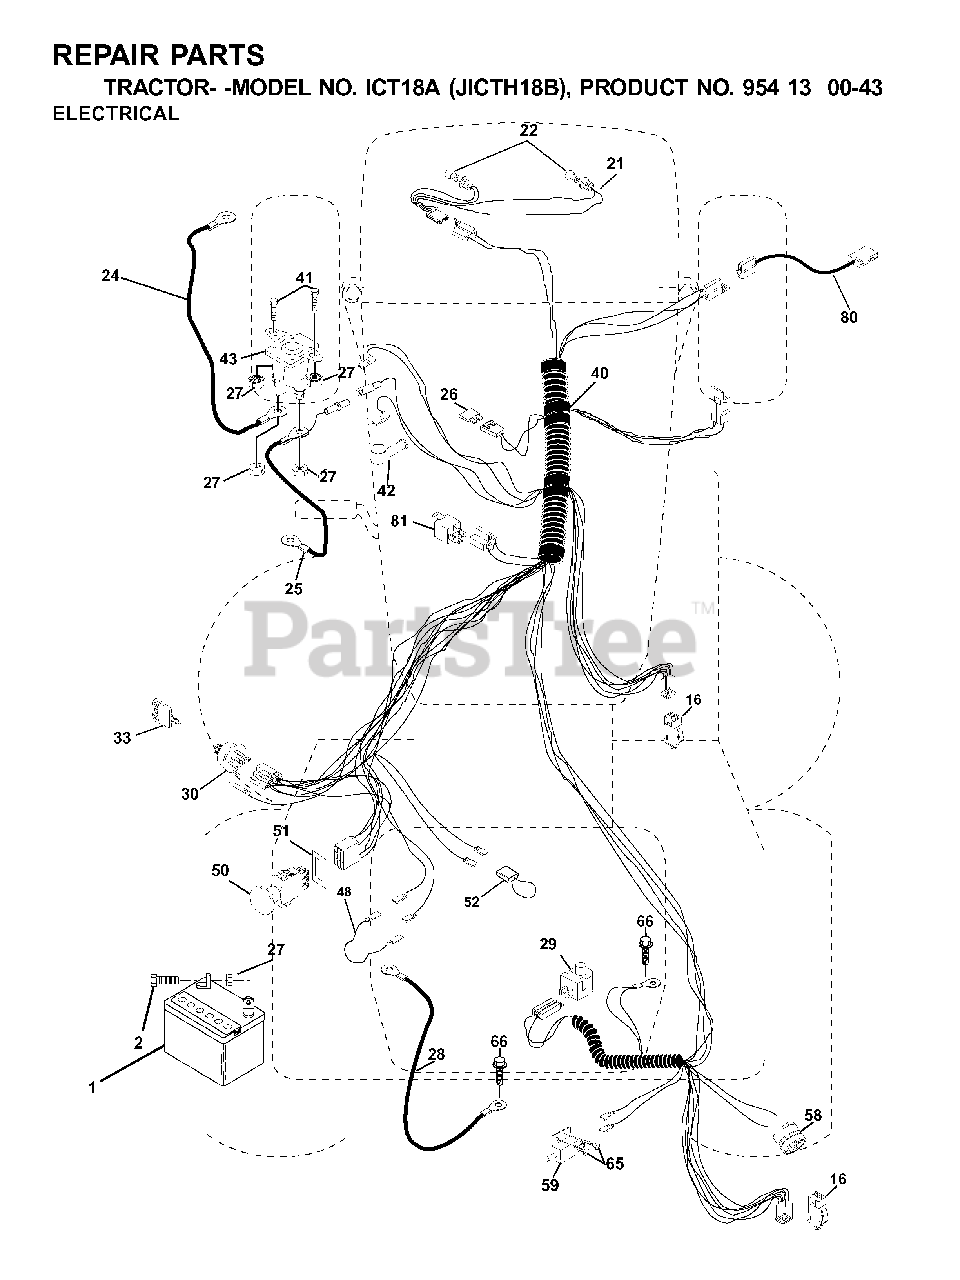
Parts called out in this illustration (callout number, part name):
1	BATTERY 12V .35 AMP
16	SWITCH INTERLOCK
21	HARNESS ASM, LIGHT W/4152J
22	LIGHTBULB
24	BATTERY CABLE GT
25	CABLE BATTERY
26	FUSE 20AMP
27	NUT
28	CABLE GROUND
29	PLUNGER SWITCH (COLOR:OLIVE)
30	IGNITION SWITCH
33	KEY MLD GEN DELTA
40	HARNESS IGN
42	TERMINAL COVER
43	REPL BY 532 1461-54
50	SWITCH.PTO.8.TERMINAL.
51	RETAINING RING
52	WIRE PROTECTION LOOP
58	BUZZER
80	HARNESS, CLUTCH
81	RELAY.ASSY.T
